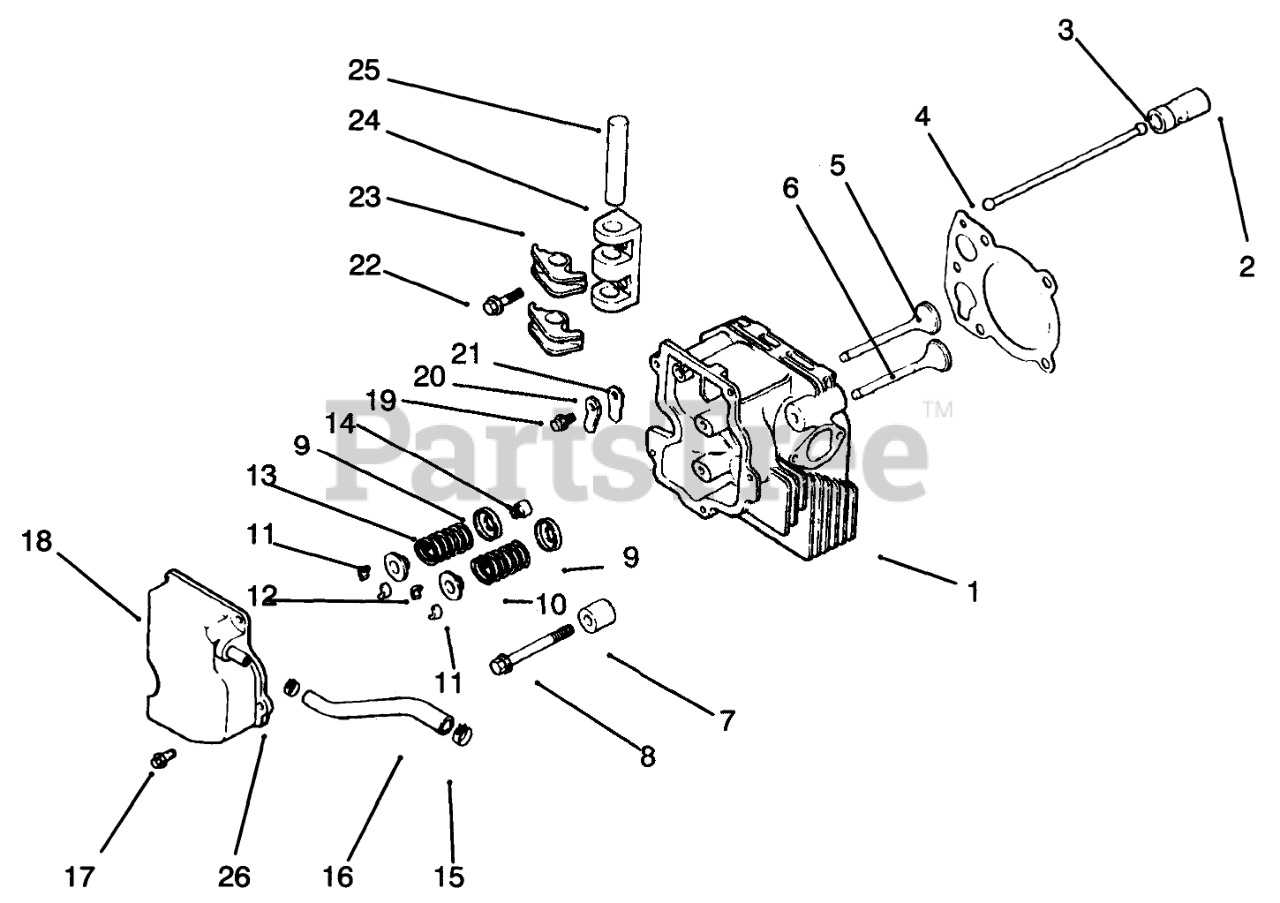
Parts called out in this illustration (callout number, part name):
1	Cylinder Head
2	Lifter-Valve
3	Rod-Push
4	Gasket-Cylinder Head
5	Valve-Intake STD
6	Valve-Exhaust STD
7	Spacer-Head Bolt
8	Screw-Cylinder Head
9	Retainer-Spring
10	Spring-Valve Intake
11	Cap-Valve Spring
12	Kit-Retainer
13	Spring-Valve, Intake
14	Seal
15	Clamp
16	Hose-Breather
17	Screw
18	Cover-Valve
20	Retainer-Reed
22	Screw
23	Arm-Rocker
24	Bridge-Rocker Arm
25	Shaft-Rocker Arm
26	Clamp-Hose
